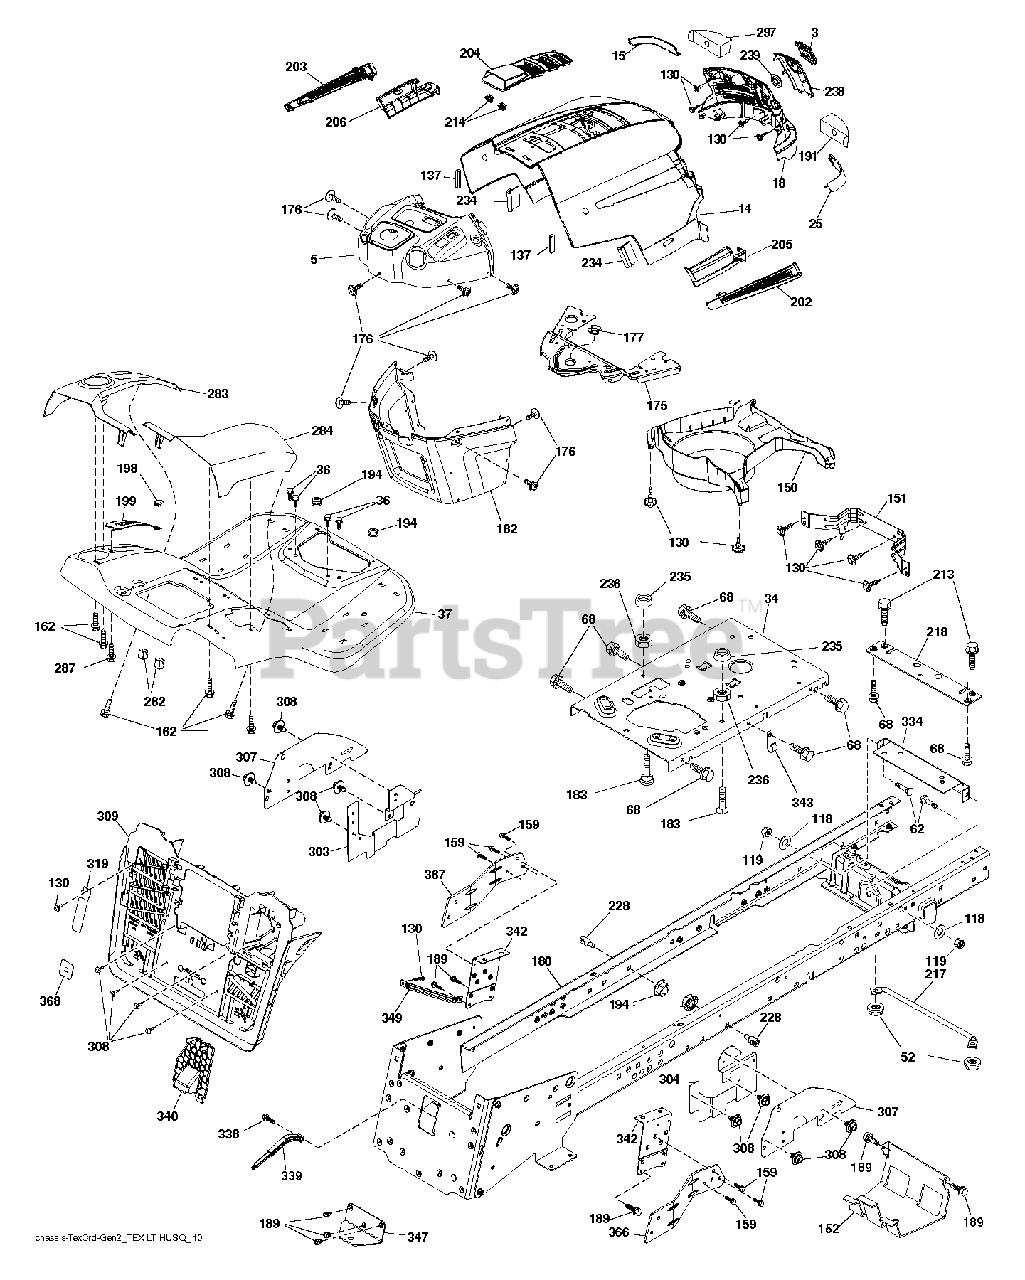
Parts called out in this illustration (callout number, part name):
3	LOGO.HUSQ.GT.LT.CROWN.H
14	HOOD.HUSQVARNA.LT.ORANGE
15	LENS.HUSQVARNA LT.RH
18	GRILLE.SVC.HUSQVARNA.GREY
25	LENS.HUSQVARNA LT.RH
34	PLATE.ENGINE.10GA.CRD.GENII
36	SCREW 5/16"
37	FENDER.TEX.SRD.CRD.FRN.GUARDS
52	LOCKNUT
62	BOLT D
68	SCREW LT
118	WASHER
130	SCREW.#10 X 0.750.BOS
137	BUMPER DASH
151	BRACKET PIVOT
152	SHIELD.BROWNING.W/TEX
159	SCREW, 3/8-16X3/4
162	SCREW.HI-LO.CONSOLE
175	CROSSMEMBER
176	SCREW.#10-24X5/8.RN.QU
177	BUSHING STEERING
180	WELDMENT.CHASSIS.TEX.CRD.GEN.2
182	DASH.LOWER.PREDATOR LT
183	BOLT.5/16-18X1-1/4 FULL THD
189	SCREW
191	INSERT.REFLECTIVE.RH.
194	NUT LOCK HEX FLANGE 5/16-18
198	INDICATOR.DECK.LIFT.RED
199	PLATE DECK LIFT
202	VENT.SIDE.HUSQVARNA.LT.RT
203	VENT.SIDE.HUSQVARNA.LT.LFT
204	SUBASM.TOP.VENT.HUSQ.LT
205	SKIRT.SIDE.HUSQVARNA.LT.RT
206	SKIRT.SIDE.HUSQVARNA.LT.LEFT
213	BOLT
214	CLIP.RETAINER.TINNER.
217	ROD.PIVOT.HOOD
218	X-PIECE.HOOD.STOP.NON/
228	STUD.FASTNER.W/ANTI-ROTATE
234	BUMPER.HOOD.TEX.HUSQVARNA
235	SPACER FENDER
236	NUT.CENTERLOCK.5/16-
238	TRIM.HUSQ LT.668
282	CLIP.RETAINER.CONSOLE.LT.HUSQ
283	CONSOLE.DECKLIFT.CRDII.498
284	CONSOLE.PEDAL.HYDRO
287	SCREW 1/4X20
297	INSERT REFLECTIVE
303	SHIELD.LWR.LH.LT.30"CRDSRD.PNT
304	SHIELD.LWR.RH.LT30DECK.PNT.BLK
307	SHIELD.UPPER.CRD.SRD.ISO
308	BOLT, 5/16-18 X 1 3/4
309	BACKPLATE.ASM.CRDII.ANTIROTAT
319	LEVER.BAG.CRDII.ANTIROTATION
334	BRACKET.ENGINE
338	BOLT BOLT SHOULDER
339	LEVER LEVER BAGGER
340	BATTERY.DOOR.TEX.CRD.GEN.2,1
342	SUPPORT SUPPORT FENDER
343	CLIP CLIP
347	HITCH HITCH TOW TEX CRD GEN 2
349	BRACKET.SUPPORT.LRVB/CRD
366	BRACKET.RH.FRONT.BAGGER.BLACK
367	BRACKET.LH.FRONT.BAGGER.BLACK
368	FULL.LEVER.BAGGER.TEX.CRD
